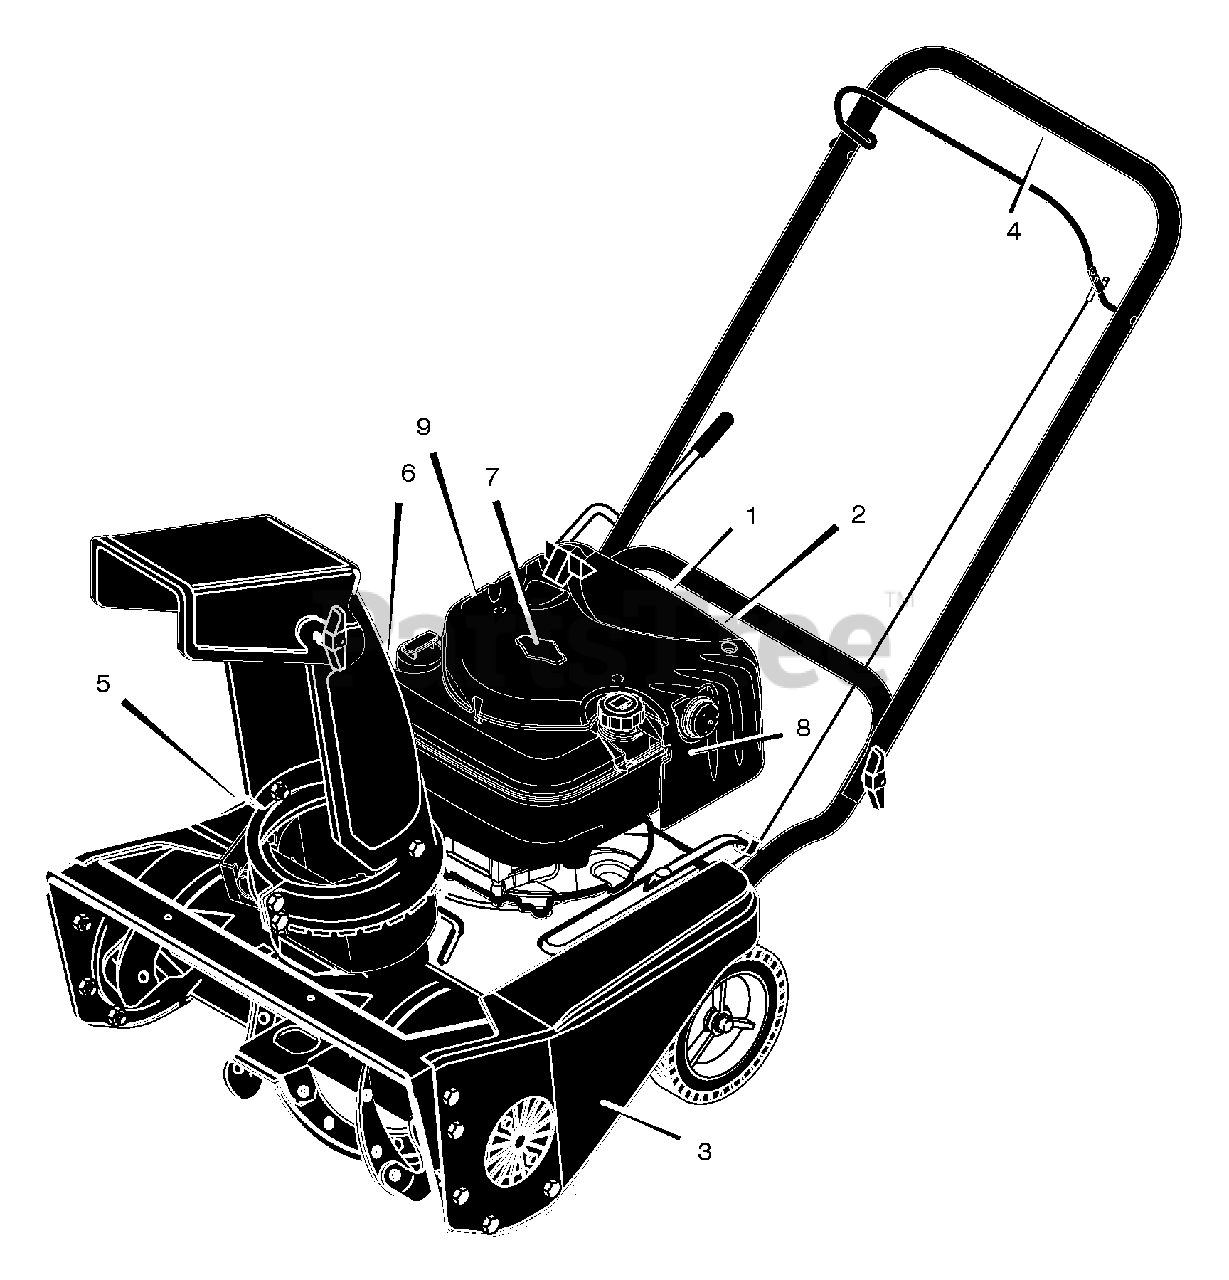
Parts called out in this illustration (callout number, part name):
1	Decal, 4hp / 21"
2	Decal, Choke
3	Decal, Belt Instruction (inside cover)
4	Decal, Auger Control Lever
5	Decal, Danger Auger (Foot)
6	Decal, Danger Chute (Hand)
7	Decal, Briggs & Stratton
8	Decal, Primer Bulb
9	Decal, Hot Surface
